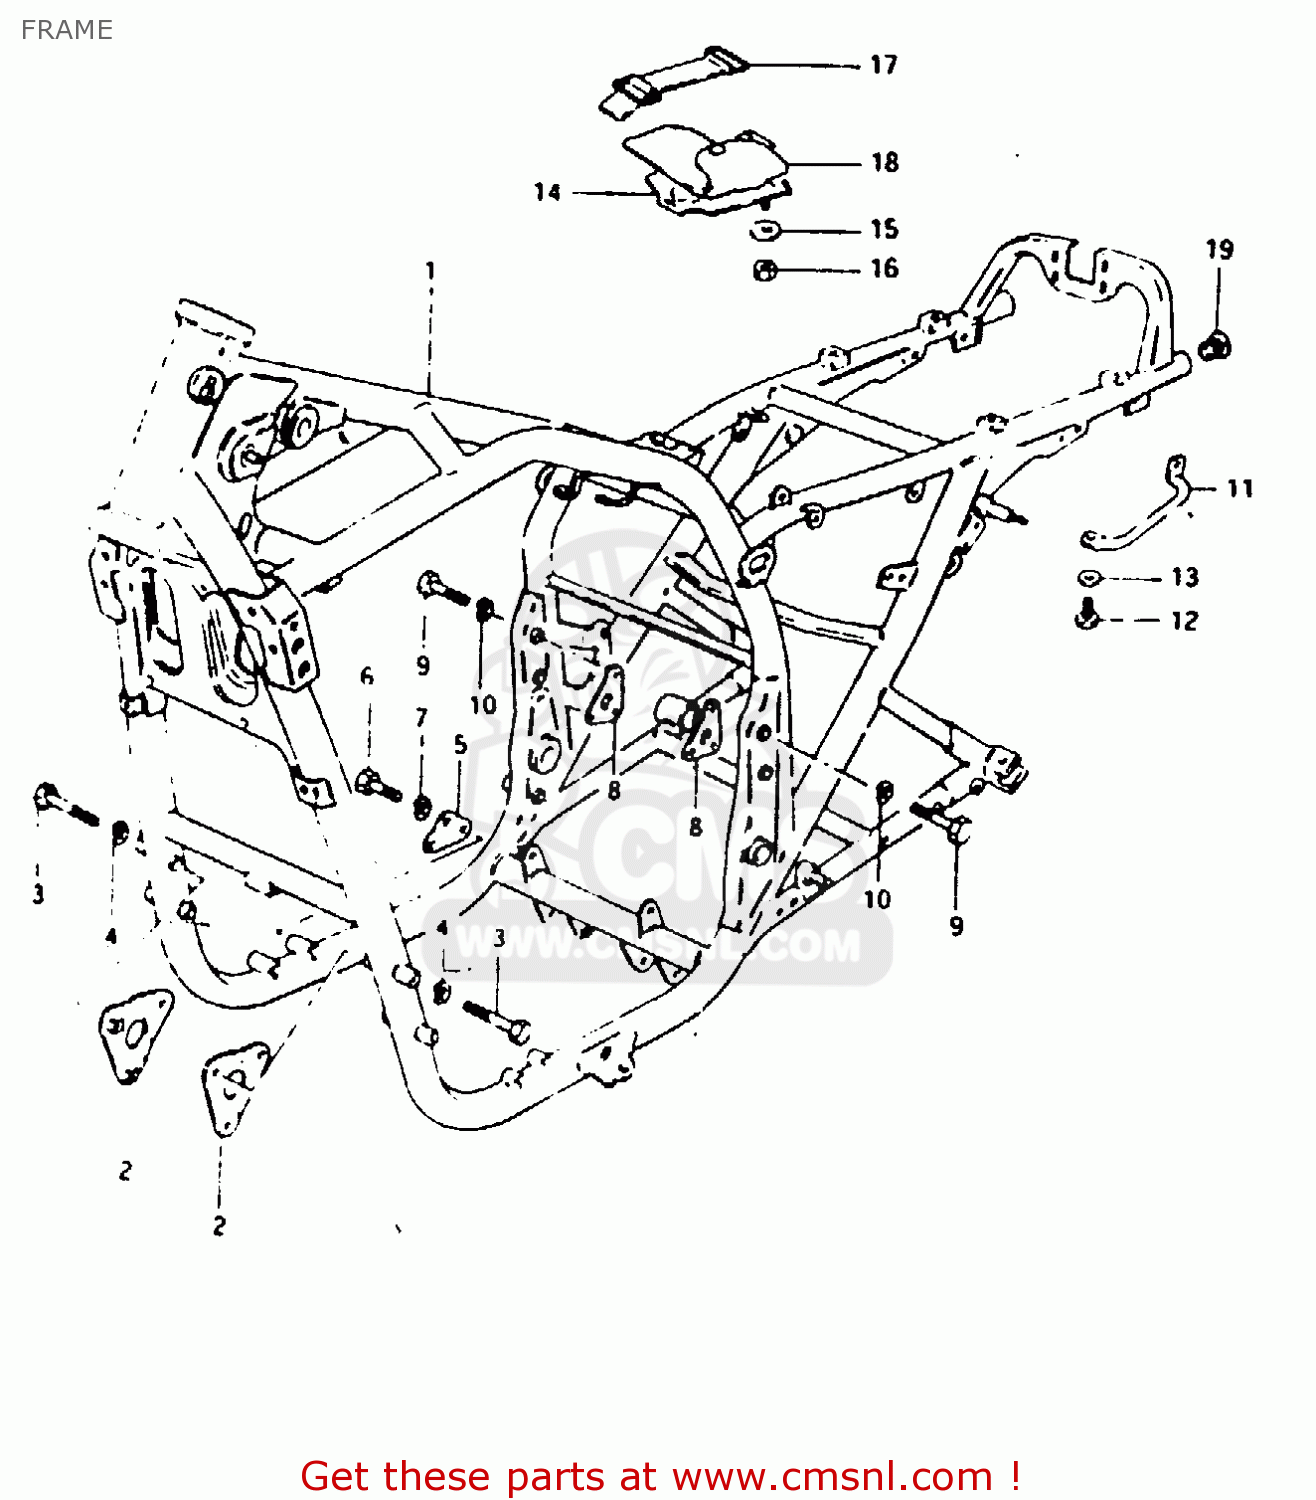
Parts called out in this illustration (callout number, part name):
1	FRAME (SILVER)
2	PLATE,ENGINE MOUNTING
3	BOLT(8X65)
4	LOCK WASHER
5	PLATE,ENG MTG NO.2
6	BOLT 8X16
7	LOCK WASHER
8	PLATE,ENG MTG NO.4
9	BOLT
10	LOCK WASHER
11	GRIP,STAND
12	BOLT
13	WASHER
14	HOLDER,TOOL
15	WASHER(6.5X30X1.6)
16	NUT
17	BAND
18	TOOL SET
19	CAP(OD:26)
